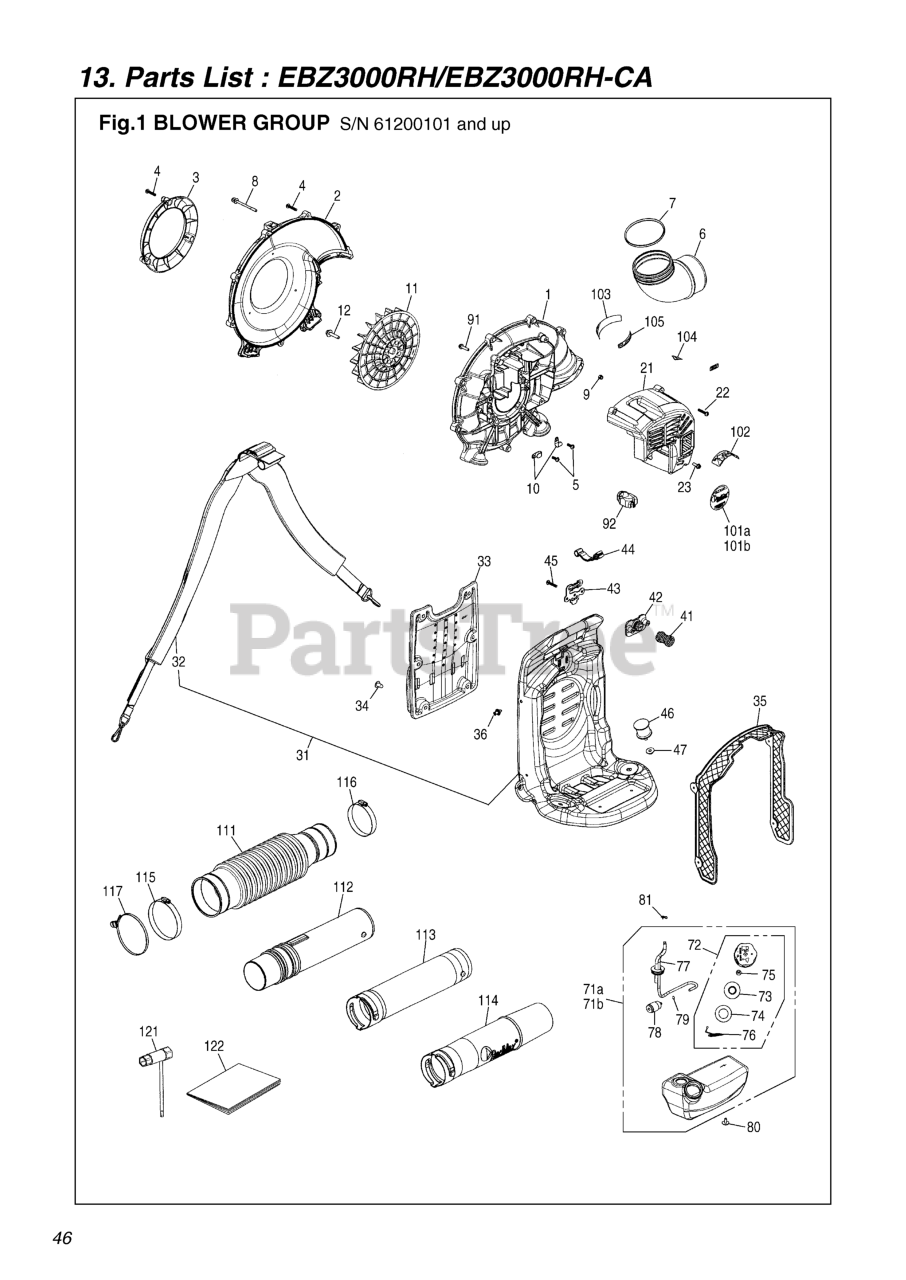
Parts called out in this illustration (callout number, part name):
1	VOLUTE CASE
2	COVER VOLUTE
3	FUNNEL
4	SCREW
6	ELBOW
8	SCREW
9	NUT
10	CLAMP
12	BOLT
21	COVER, ENGINE
22	SCREW
23	BOLT, TORX
31	FRAME ASSY
32	BAND ASSY
33	PAD
34	CLIP
35	NET
36	CLIP
42	HOLDER, SPRING
45	SCREW
46	DAMPER, LOWER
47	NUT
71B	TANK ASSY
72	CAP ASSY
73	HOLDER ASSY
74	PACKING
75	FILTER
76	STOPPER
77	PIPE COMP
78	FILTER ASSY
79	CLIP
80	SCREW
81	CLIP
91	BOLT TORX
92	COVER
101B	LABEL, RECOIL
102	LABEL, CAUTION
103	LABEL, NET
104	LABEL, HOTMARK
105	LABEL, SOUND
111	HOSE
112	SWIVEL JOINT
113	PIPE, STRAIGHT
114	PIPE, END
115	CLAMP
116	CLAMP
117	BAND
122	MANUAL, EBZ3000
